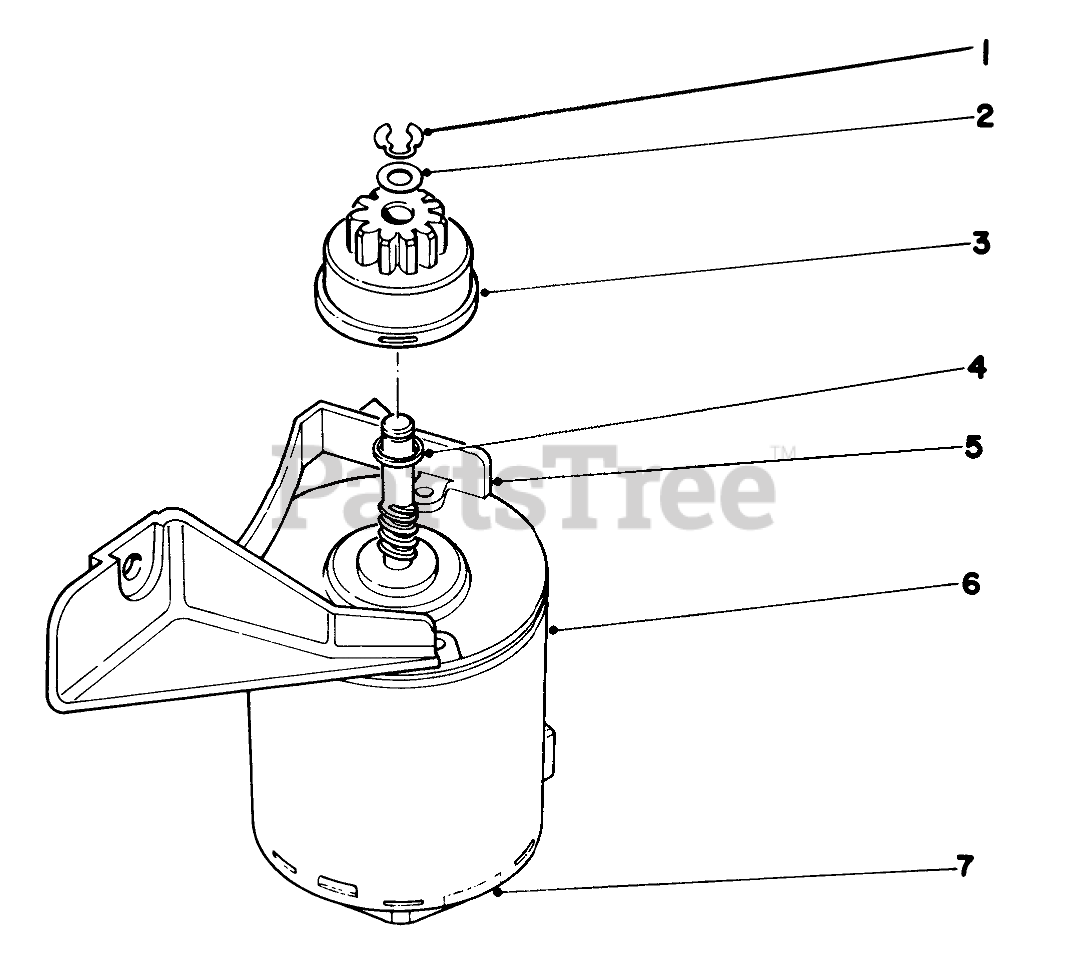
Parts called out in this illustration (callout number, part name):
1	Retaining Ring
2	WASHER
3	PINION ASM
4	Spacer
5	Mounting Bracket
6	Starter Motor
7	End Plate
